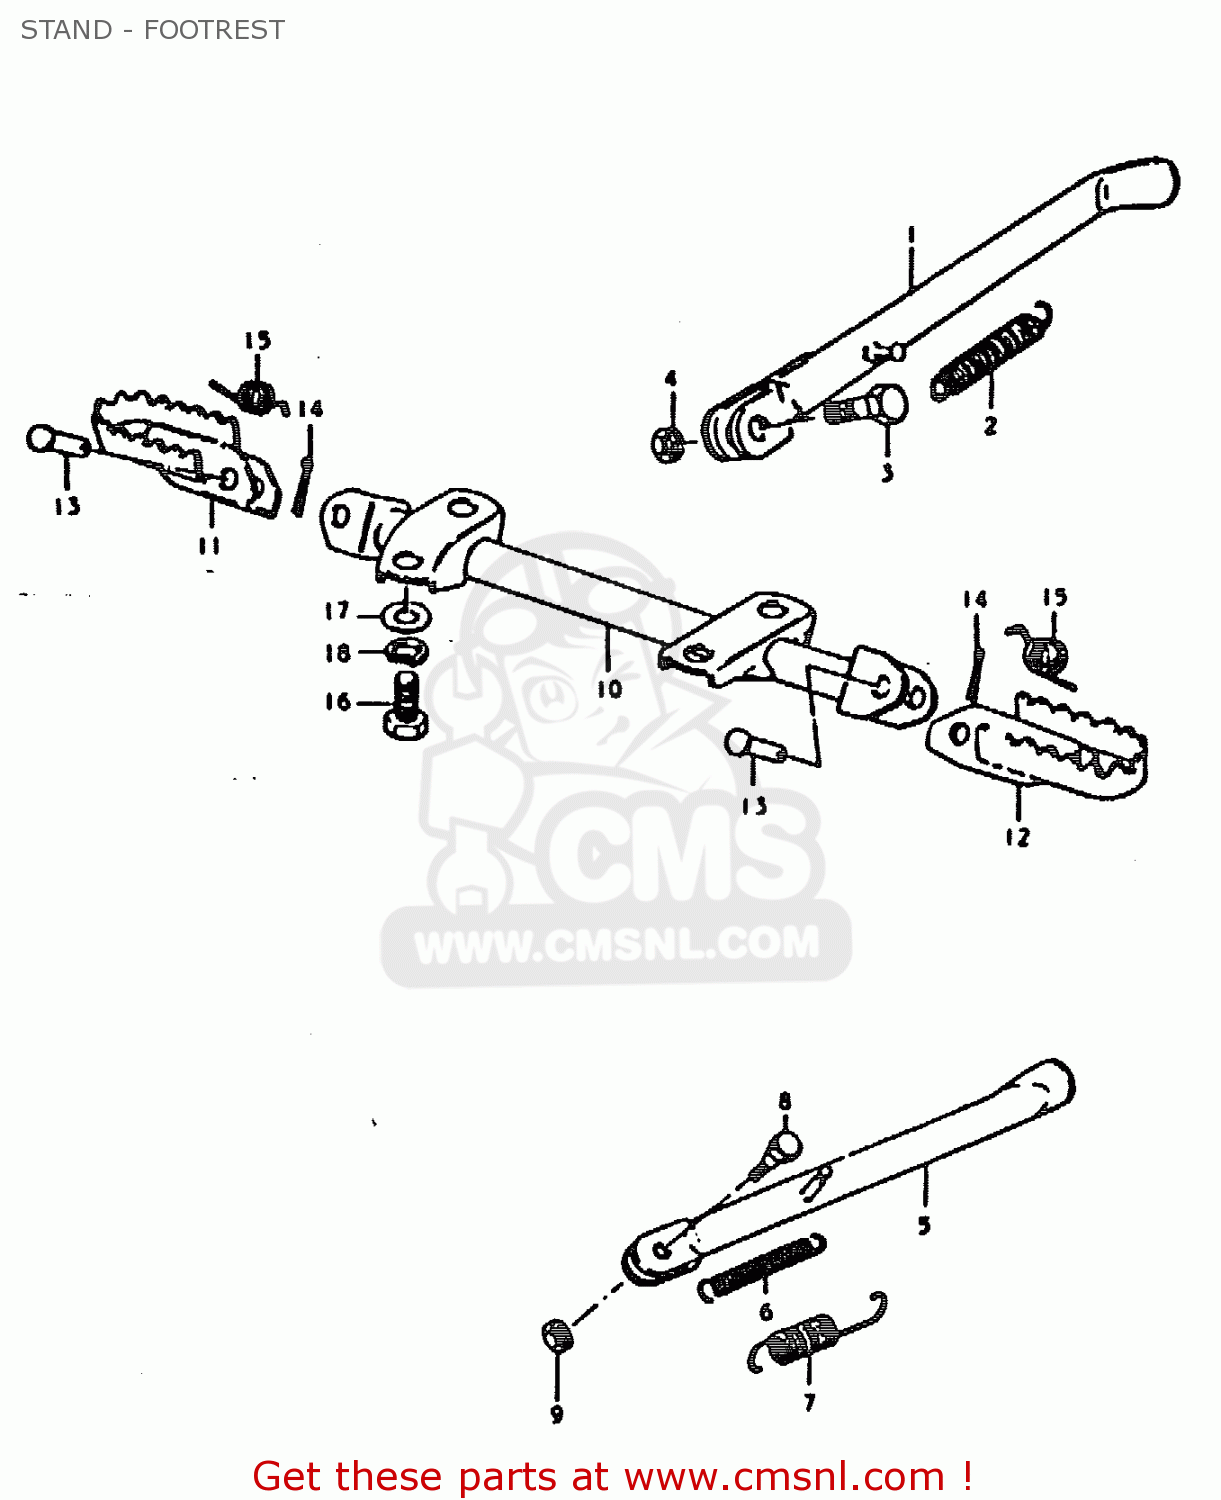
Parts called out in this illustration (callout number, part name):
1	STAND,PROP
2	SPRING
3	BOLT(10X30)
4	NUT
10	BAR,FR FOOTREST
11	FOOTREST,FR,R
12	FOOTREST,FR,L
13	PIN
14	PIN 20X20
15	SPRING
16	BOLT
17	WASHER
18	WASHER,LOCK,8.
